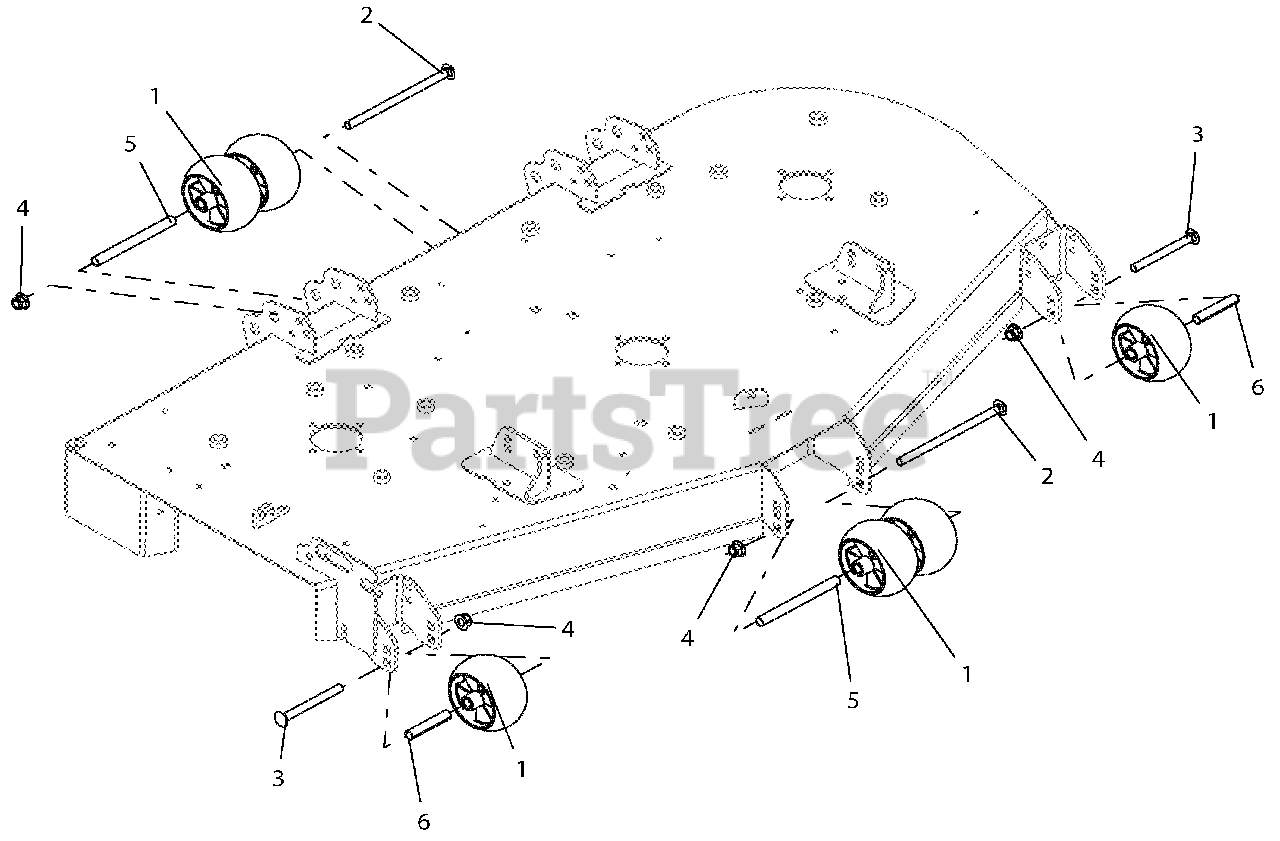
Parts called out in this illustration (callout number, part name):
1	ANTI-SCALP WHEEL - 5X3 CTR
2	BLT-RDHDSQNK .50-13X8.50 Y
3	BLT-RDHDSQNK .50-13X5.00 G5 CYWZ
4	NUT-LK-NYL-FLG .50-13 YCWZ
5	SPACER, .510 X .625 X 6.50
6	SPACER, .510X.625X3.35
